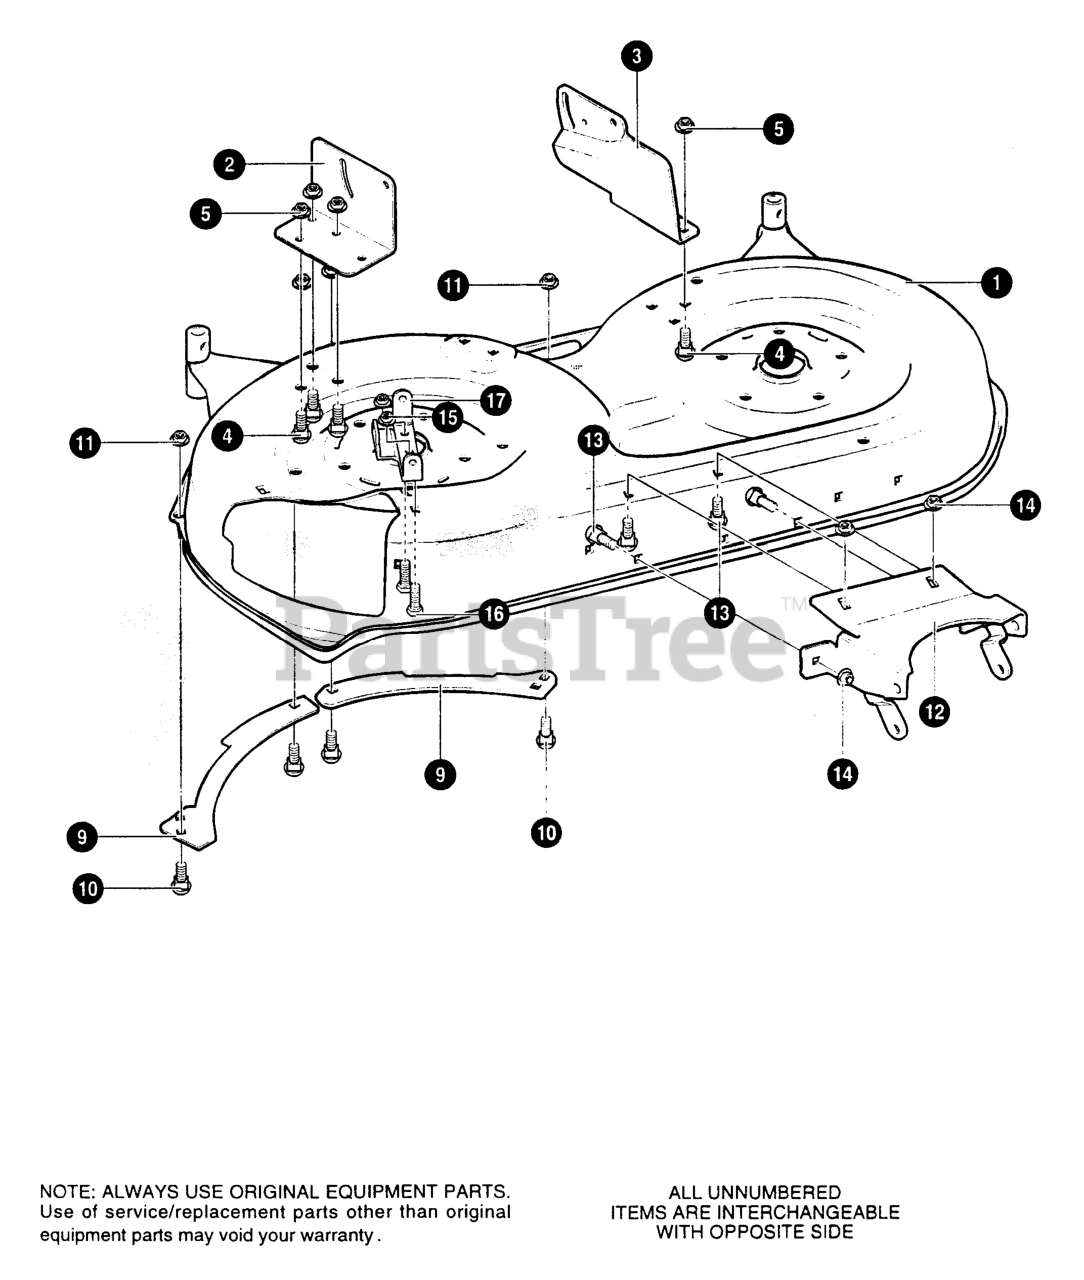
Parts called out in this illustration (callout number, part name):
1	ASSY, WELD BLD HSING 42"
2	BRACKET, DECK RH
3	BRACKET, DECK LH
4	BOLT, 5/16-18X.63 CARR.
5	NUT, 5/16-18 HEXWDFLLK WHIZ
9	TOEGUARD, FLANGE
10	BOLT, 5/16-18X.63 CARR.
11	NUT, 5/16-18 WDFLLK (15X88)
12	ASSY, FRONT BRACKET ROLLER
13	BOLT, 5/16-18X.63 CARR.
14	NUT, 5/16-18 HEXWDFLLK WHIZ
15	NUT, 5/16-18 WDFLLK (15X88)
16	BOLT, 5/16-18X.63 CARR.
17	BRACKET, CHUTE ATTACHMENT
